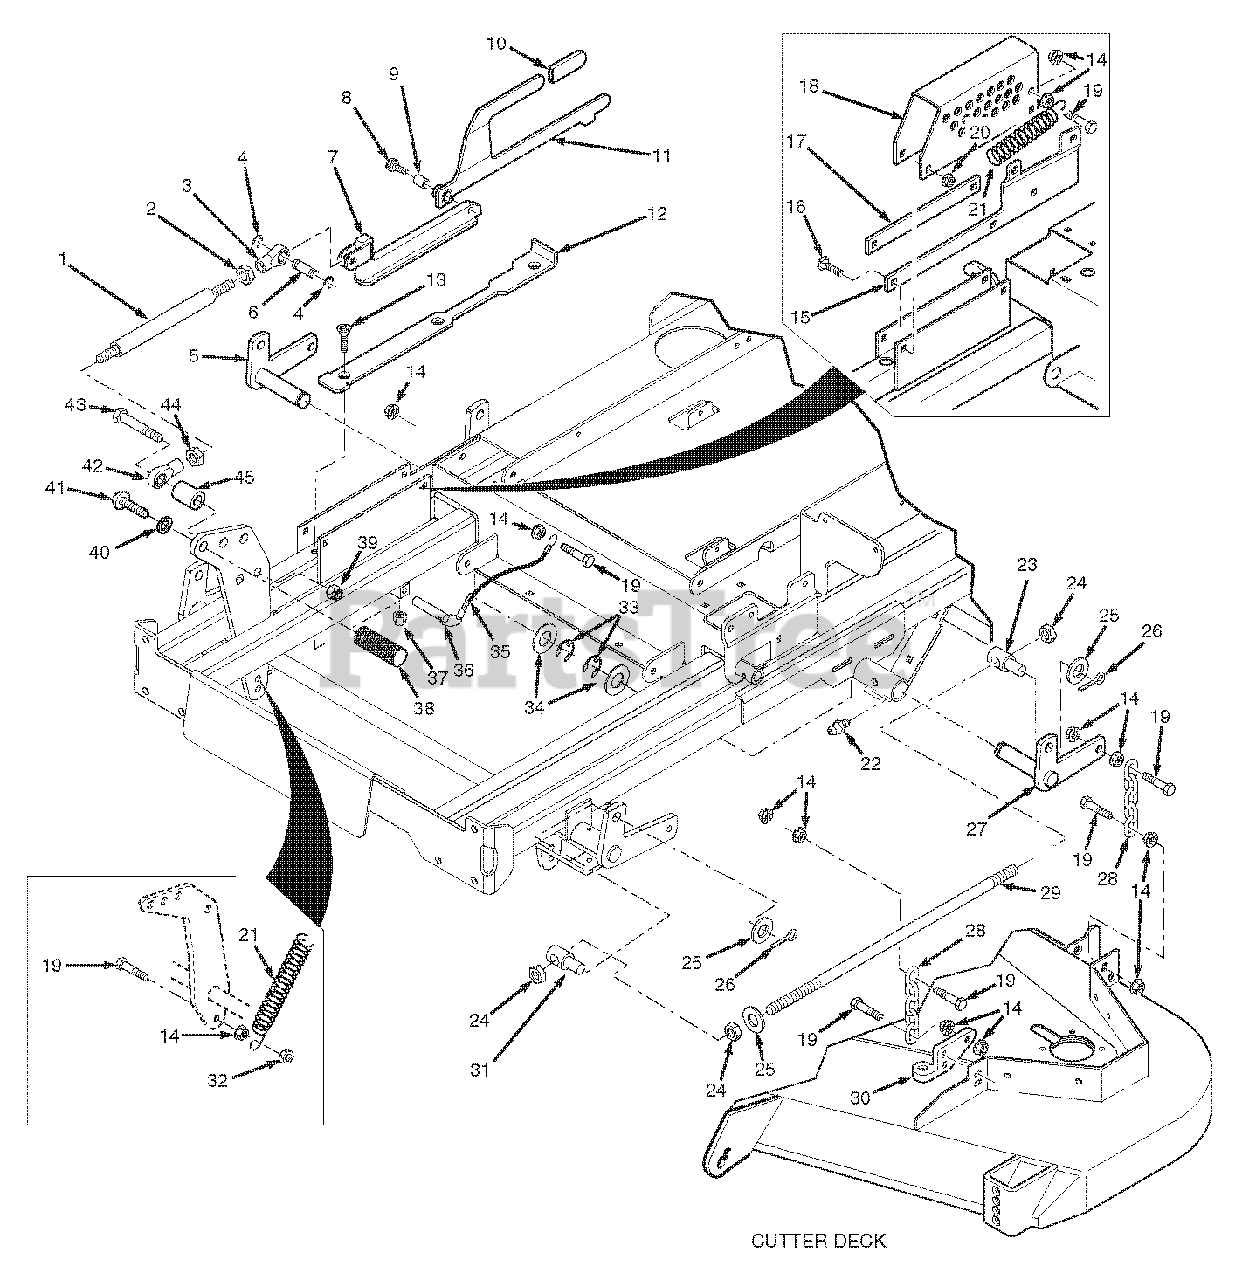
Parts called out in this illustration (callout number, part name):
1	Link, Deck Lift
2	Nut, Jam 1/2-20 LH
3	Rod End, Female - 1/2-20 LH
4	Ring, Retaining 1/2" External "E"
5	Bellcrank Weldment, RH Rear
6	Pin, Decklift
7	Slide Weldment, Height Adjustment
8	Bolt, Shoulder 1/2 x 3/4"
9	Bushing, .502 ID.
10	Grip, Deck Latch
11	Deck Latch
12	Lockplate, Decklift
13	Screw, Cap 5/16-18 x 3" FHHS
14	Nut, Hex Serrated Flange 3/8-16
15	Guide, Long
16	Bolt, Carriage 5/16-18 x 1"
17	Guide, Short
18	Bracket, Cutting Height Adjustment
19	Bolt, Hex Head 3/8-16 x 1-1/2"
20	Nut, Hex Serrated Flange 5/16-18
21	Spring, Helper (61" & 72" Cutter Decks Only)
22	Grease Fitting
23	Swivel Joint, LH
24	Nut, Hex 5/8-11
25	Flatwasher, 5/8" (.656 x 1.312 x .095)
26	Cotter Pin, 3/16 x 1"
27	Bellcrank Weldment, LH Rear
28	Chain
29	Stud, 5/8-11 x 26.0"
30	Lever Assembly, Deck Level
31	Swivel Joint, RH
32	Locknut, 3/8-16 Center Lock
33	Ring, Retaining 1" External "E"
34	Flatwasher, 1" (1.062 x 1.50 x .048)
35	Lanyard, Deck Height Pin
36	Ring Pin, 1/2 x 3.06"
37	Nut, 3/8-16 Elastic Stop
38	Foot Pedal, Height Adjustment
39	Nut, Hex Elastic Stop 1/2-13
40	Lockwasher, 5/8"
41	Capscrew, 5/8-11 x 1-1/2"
42	Rod End, Female - 1/2-20 RH
43	Bolt, Hex Head 1/2-13 x 3"
44	Nut, Jam 1/2-20 RH
45	Spacer, Decklift Pedal
